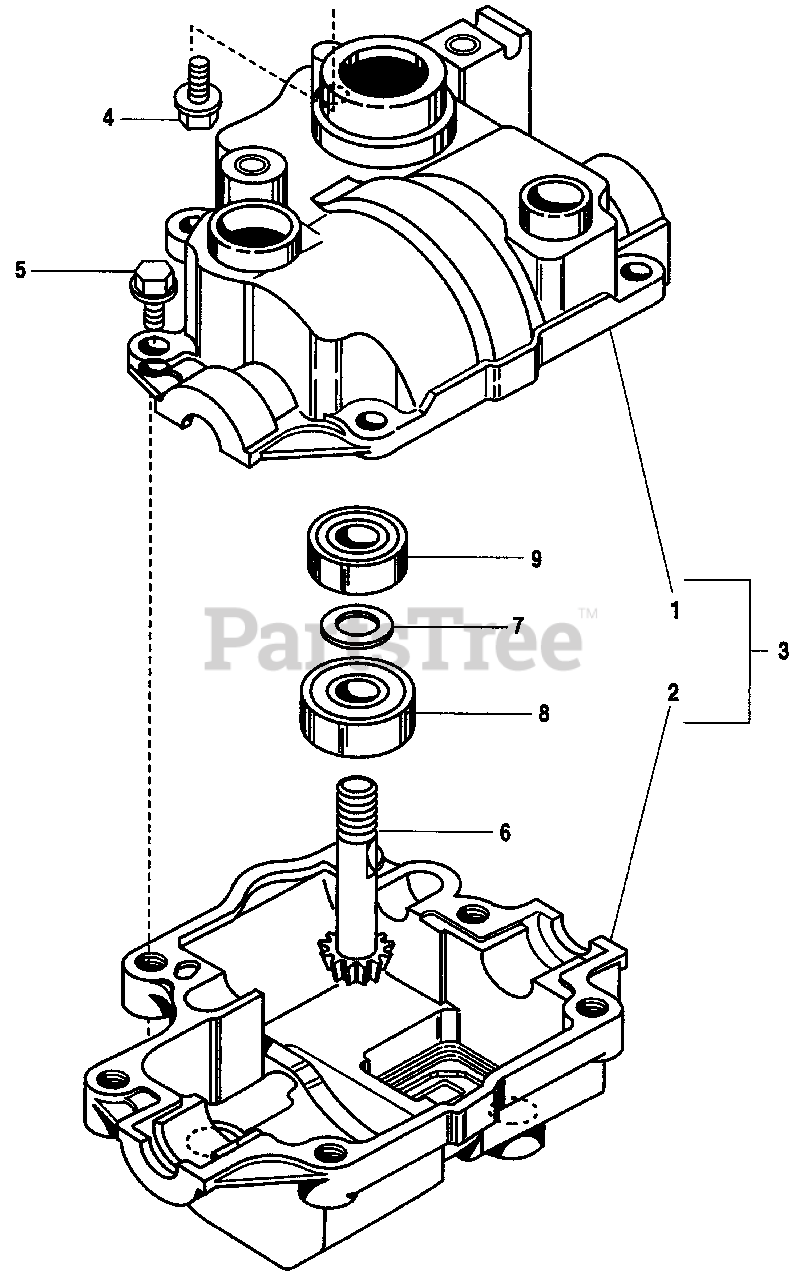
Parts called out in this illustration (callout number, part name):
3	TRANSMISSION CASE KIT
4	SCREW, Self-tapping
5	SCREW, Self-tapping
6	SHAFT, Input
8	BALL BEARING
9	BALL BEARING
